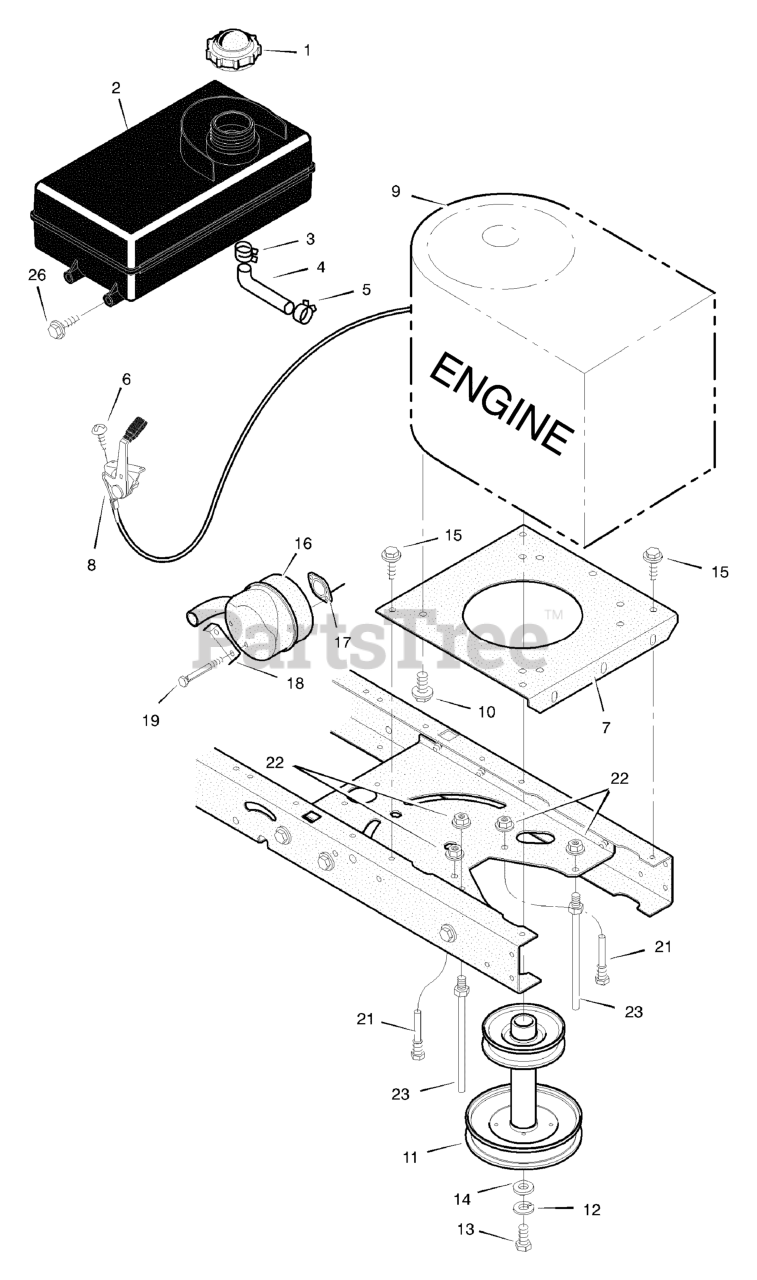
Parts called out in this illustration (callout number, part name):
1	Fuel Cap
2	Fuel Tank
3	Hose Clamp
4	Fuel Line (Must cut to length)
5	Hose Clamp
7	Plate, Engine
8	Throttle Control
9	Engine, Tecumseh *
10	Bolt, Engine Mount
11	STACK PULLEY ASSEMBLY
12	Lockwasher
13	Bolt, Hex
16	Muffler
17	GASKET, Exhaust
18	Lock, Screw
21	Guide, Belt
22	Nut, Flange
23	Guide, Belt
